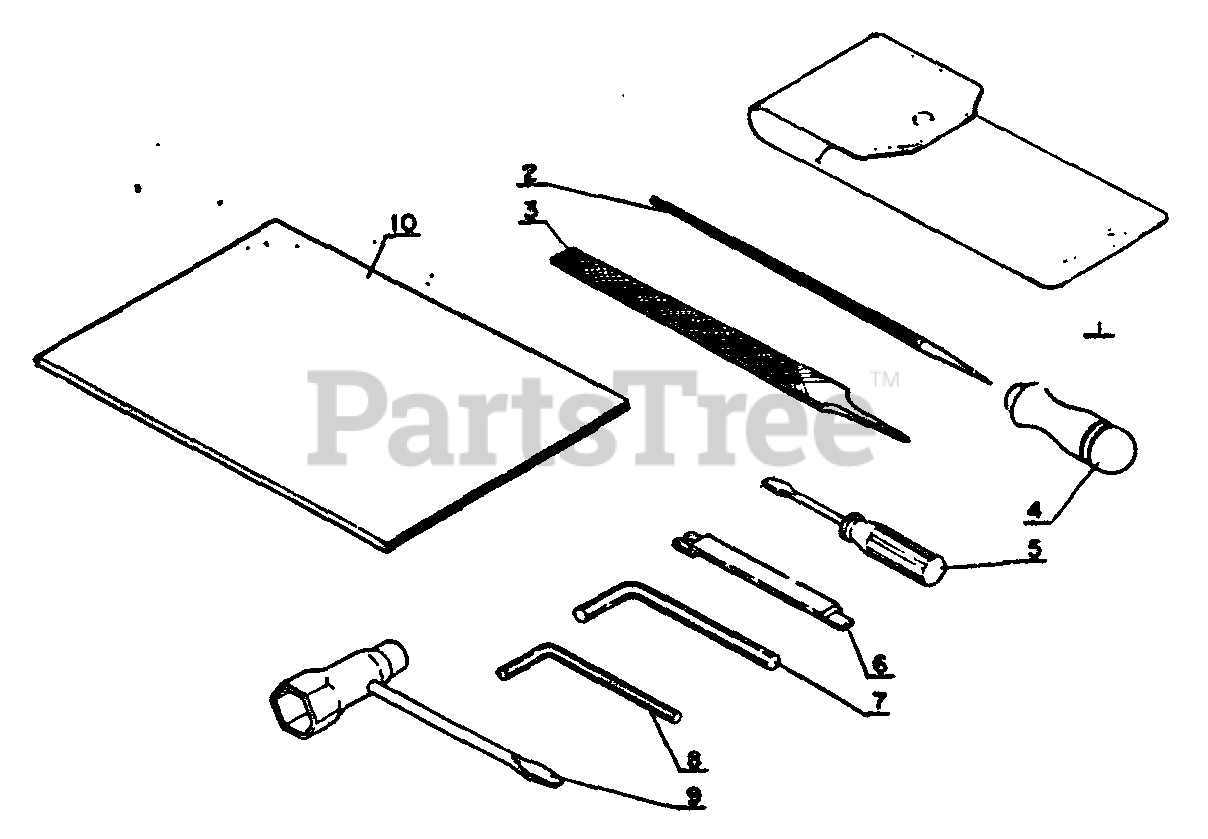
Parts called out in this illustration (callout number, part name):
1	BAG, TOOL
2	ROUND FILE
3	FLAT FILE
4	FILE GRIP
5	SCREWDRIVER
6	GAUGE, DEPTH
7	WRENCH, ALLEN 4 MM
8	WRENCH, ALLEN 3 MM
9	T-WRENCH 10×19 MM
